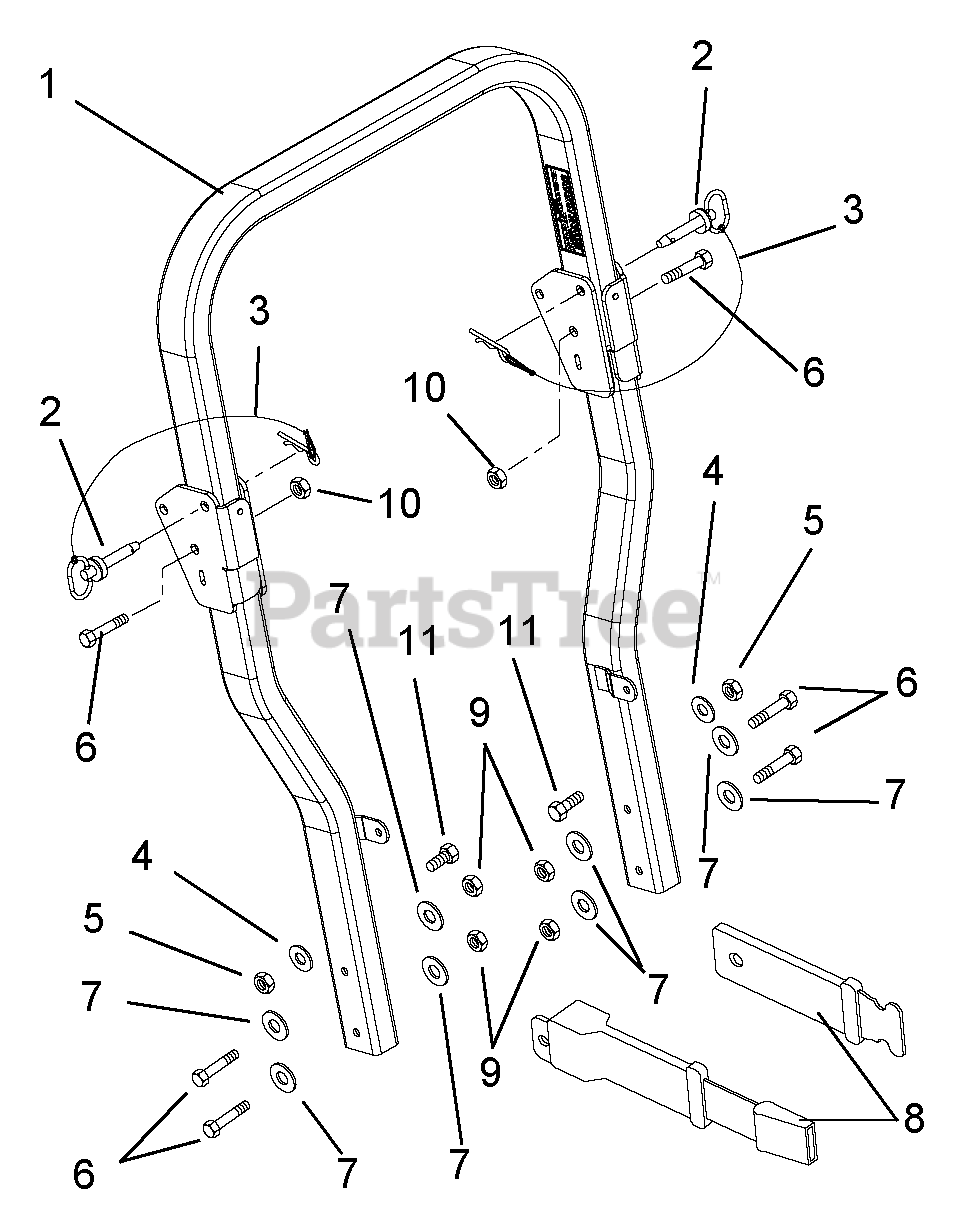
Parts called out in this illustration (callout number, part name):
1	KIT,FOLDABLE ROPS-200 SERIE
2	HITCH PIN--ROPS BAR
3	LANYARD, U-LOCK NYLON
4	@WSHR-FL-STL.50X1.25X.083 YWZC
5	@NUT-LK-CTR .44-14 YWZC
6	@BLT-HEX .50-13X3.25 GR5 YWZC
7	@WSHR-FL-STL.563X1.38X.109YWZC
8	ASSY, SEAT BELT
9	@NUT-LK-NYL .50-13 YWZC
10	@NUT-LK-CTR .50-13 YWZC
11	@BLT-HEX .44-14X1.00 GR5 YWZC
